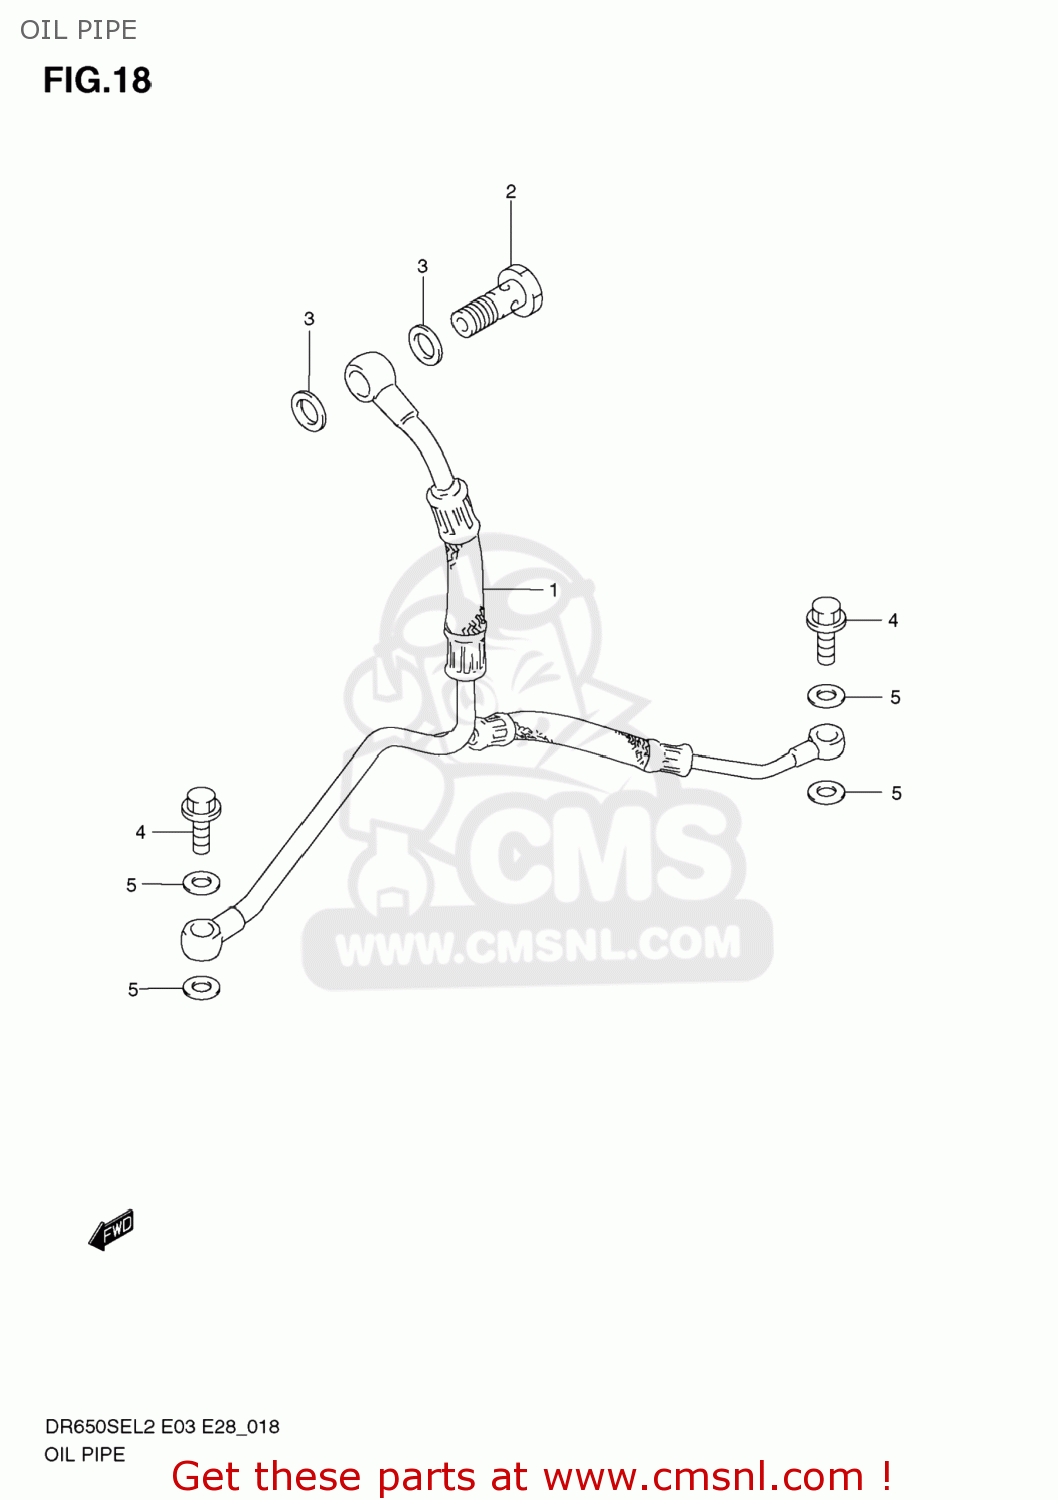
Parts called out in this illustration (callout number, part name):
1	PIPE,T/M & CSHAFT OIL
2	BOLT UNION
3	GASKET(12X17X1) (NAS)
4	BOLT UNION
5	GASKET(10.1X16X1) (NAS)
